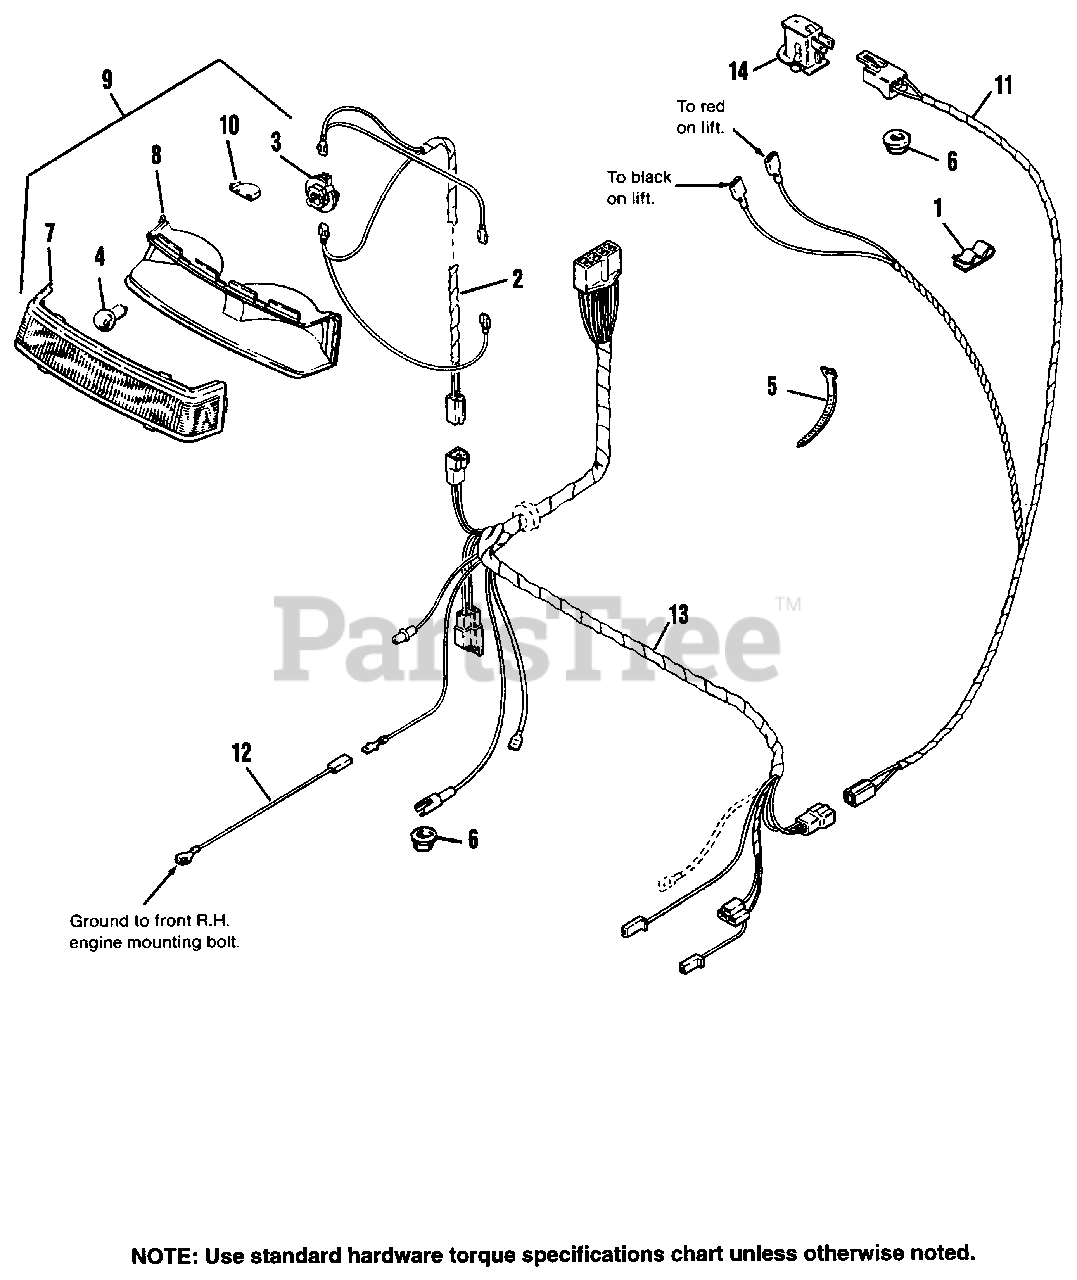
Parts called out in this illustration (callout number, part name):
1	CLIP, Speed
2	WIRE ASSY., Headlight
3	SOCKET, Bulb
4	BULB, Headlight, 12.8V
6	BUSHING, Snap, Small
7	LENS, Headlight
8	BEZEL, Headlight
9	HEADLIGHT ASSY. (Incl. Ref. Nos. 3, 4, 7, 8 & 10)
10	HEAT SHIELD
11	WIRE ASSY., Seat Switch and Lift
12	WIRE ASSY., Engine Ground
13	HARNESS ASSY., Lower
14	SWITCH, Seat, Operator Present
